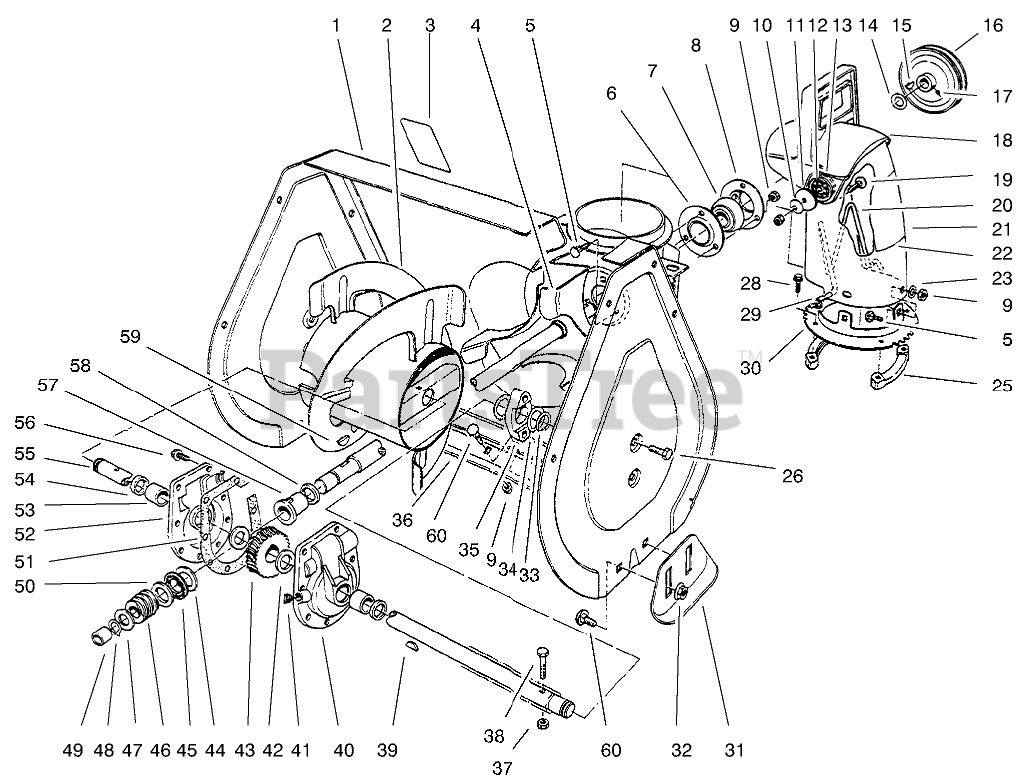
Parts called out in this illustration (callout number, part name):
1	Housing-Auger (Model No. 38072)(Incl. Ref. #3)
2	Auger-R.H.
3	DECAL-WARNING, AUGER
4	Shaft & Impeiler
5	SCREW-CARR
6	FLANGE-CUP, BEARING
7	BEARING-BALL
8	FLANGE-CUP, BEARING
9	NUT-LOCK, NI
10	WASHER-BELLEVILLE
11	WASHER-FLAT
12	PLATE-FRICTION
13	WASHER-RUBBER
14	WASHER
15	KEY-WOODRUFF
16	PULLEY
17	SCREW-SET, SQH
18	CHUTE-DEFLECTOR
19	SCREW-CARR
20	WIRE-CHUTE
21	Chute-Discharge (Model No. 38072)(Incl. Ref. #22)
22	DECAL-DANGER (only on: 38078)
23	WASHER-PLAIN
25	RING-CHUTE, RETAINER
26	SCREW-HWHTF
28	SCREW-SPECIAL
29	NUT-PUSH
30	Chute Ring
31	Skid
32	NUT-HF
33	RING-RETAINING
34	WASHER
35	BEARING-AUGER
36	Blade-Scraper
37	NUT-LOCK, NI
38	SCREW-HH
39	KEY-WOODRUFF
40	Gear Case L.H. (Incl. Ref. #53 & 54)
41	PLUG-PIPE, SQH
42	WASHER-THRUST
43	GEAR-WORM, 27T
44	WASHER-THRUST
45	BEARING-THRUST
47	WASHER-THRUST
48	Ring-Snap
49	BUSHING
50	WASHER-THRUST
51	GASKET-CASE, GEAR
52	Gear Case R.H. (Incl. Ref. #53 & 54)
53	BUSHING
54	SEAL-OIL
55	SHAFT-AUGER
56	SCREW-TAPTITE
57	BUSHING-INPUT
58	RING-QUAD
59	KEY-WOODRUFF
60	BOLT-CARR
